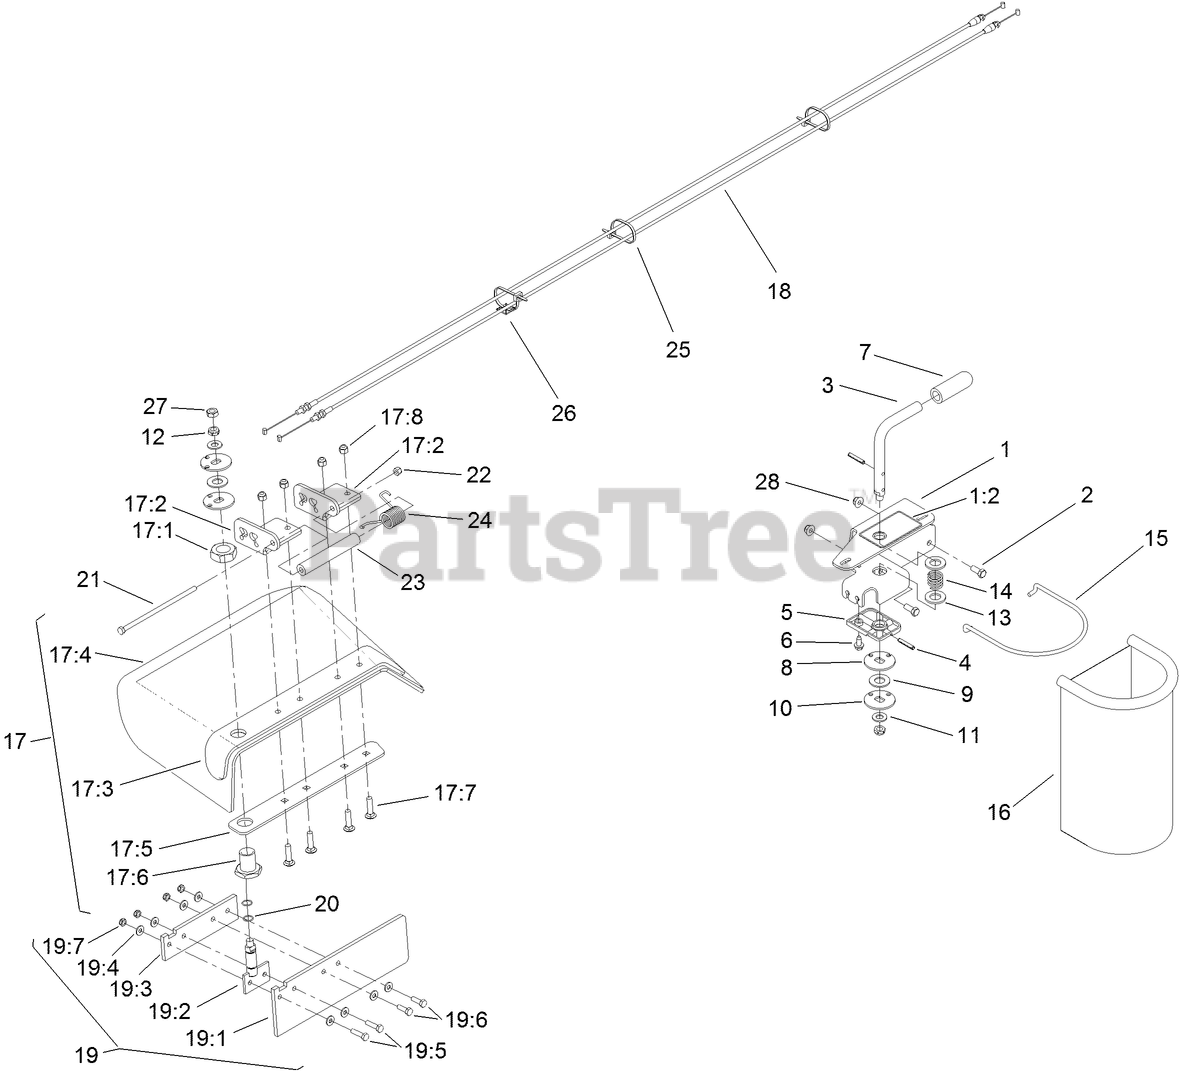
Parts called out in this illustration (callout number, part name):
1	CONTROL BRACKET ASM
1:2	DECAL-GATE, CHUTE
2	SCREW-HWH
3	HANDLE
4	PIN-ROLL
5	BLOCK-DETENT
6	SCREW-HWHTF
8	PULLEY-TOP
9	PULLEY-MIDDLE
10	PULLEY-BOTTOM
11	WASHER-FLAT
12	NUT-LOCK, NI
13	WASHER-FLAT
14	SPRING-COMPRESSION
15	ROD-BAG, TRASH
16	BAG-TRASH
17	RUBBER DEFLECTOR ASM
17:1	NUT-JAM
17:2	PLATE-HINGE
17:3	DEFLECTOR
17:4	DEFLECTOR-CHUTE, RUBBER
17:5	STRAP-DISCHARGE
17:6	HUB ASM
17:7	SCREW-CARR
17:8	NUT-LOCK, NI
19	DOOR ASM
19:1	GATE-CHUTE, RUBBER
19:2	HINGE-GATE
19:3	DOOR-SUPPORT
19:4	WASHER-FLAT
19:5	SCREW-HH
19:6	SCREW-HH
19:7	NUT-LOCK, NI
20	O-RING
21	SCREW-HH
22	NUT-LOCK, NI
23	SPACER
24	SPRING-TORSION
25	TIE-CABLE
26	MOUNT-TIE, CABLE
27	NUT-JAM
28	NUT-HF, NI
